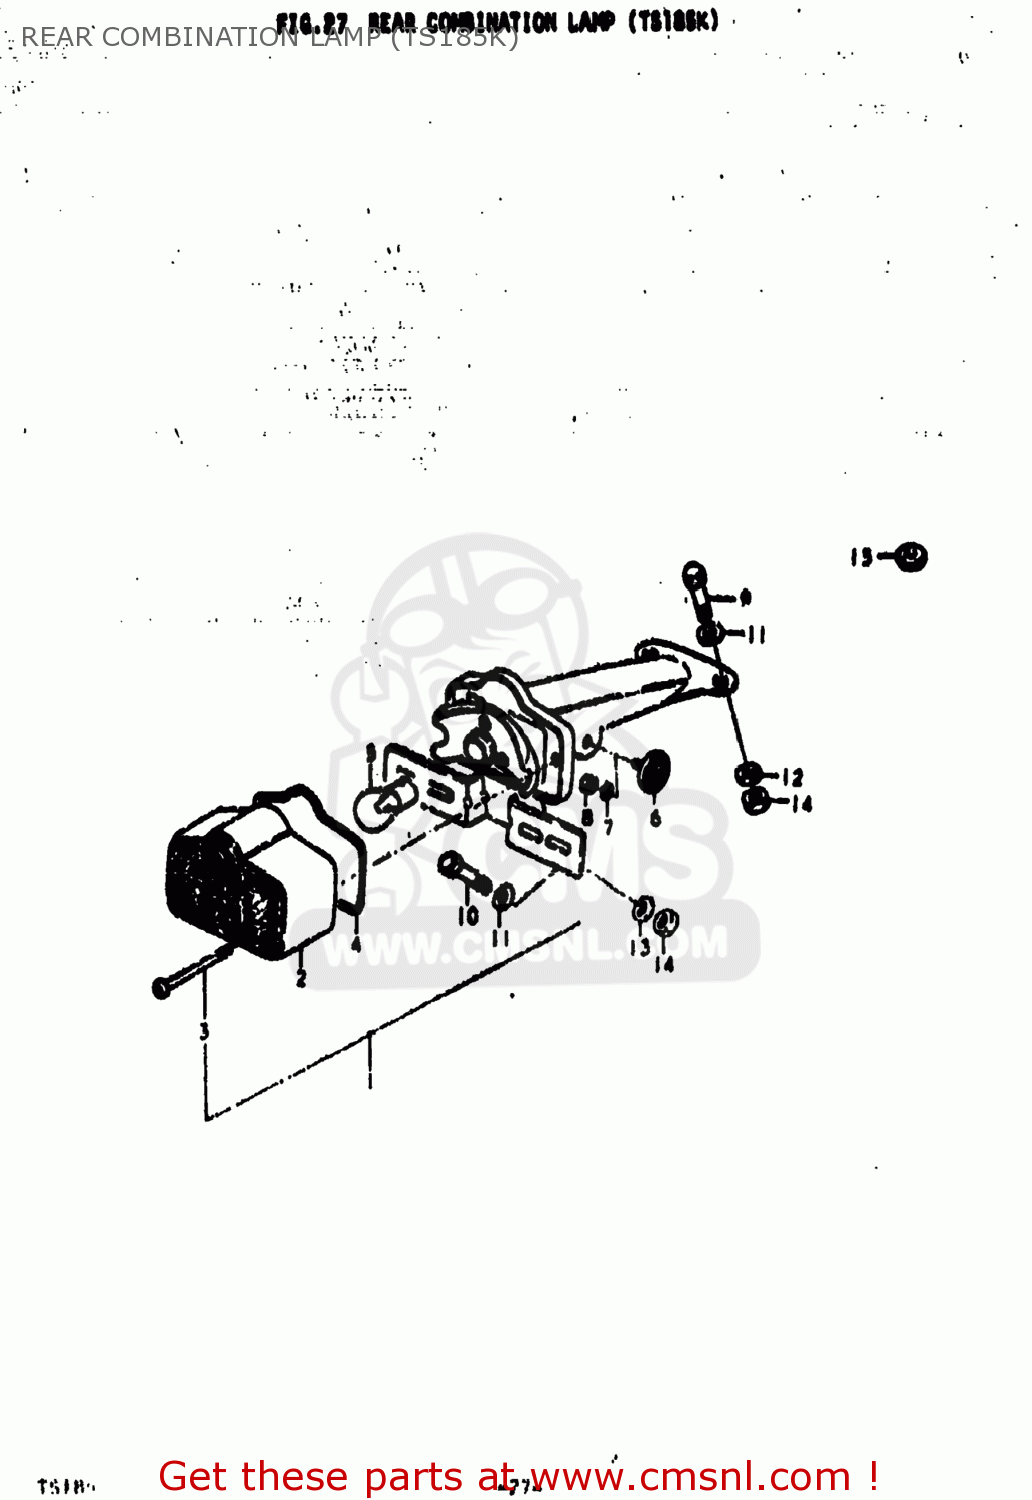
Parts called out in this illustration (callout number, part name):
1	LAMP ASSEMBLY,REAR COMBINATION
2	LENS,REAR COMBINATION LAMP
3	SCREW
4	GASKET (NAS)
5	BULB(6V32/3CP,STANLEY)
6	REFLECTOR,REFLEX
7	LOCK WASHER
8	NUT
9	BOLT 6X22
10	BOLT 6X22
11	WASHER
12	LOCK WASHER
13	LOCK WASHER
14	NUT
15	GROMMET
